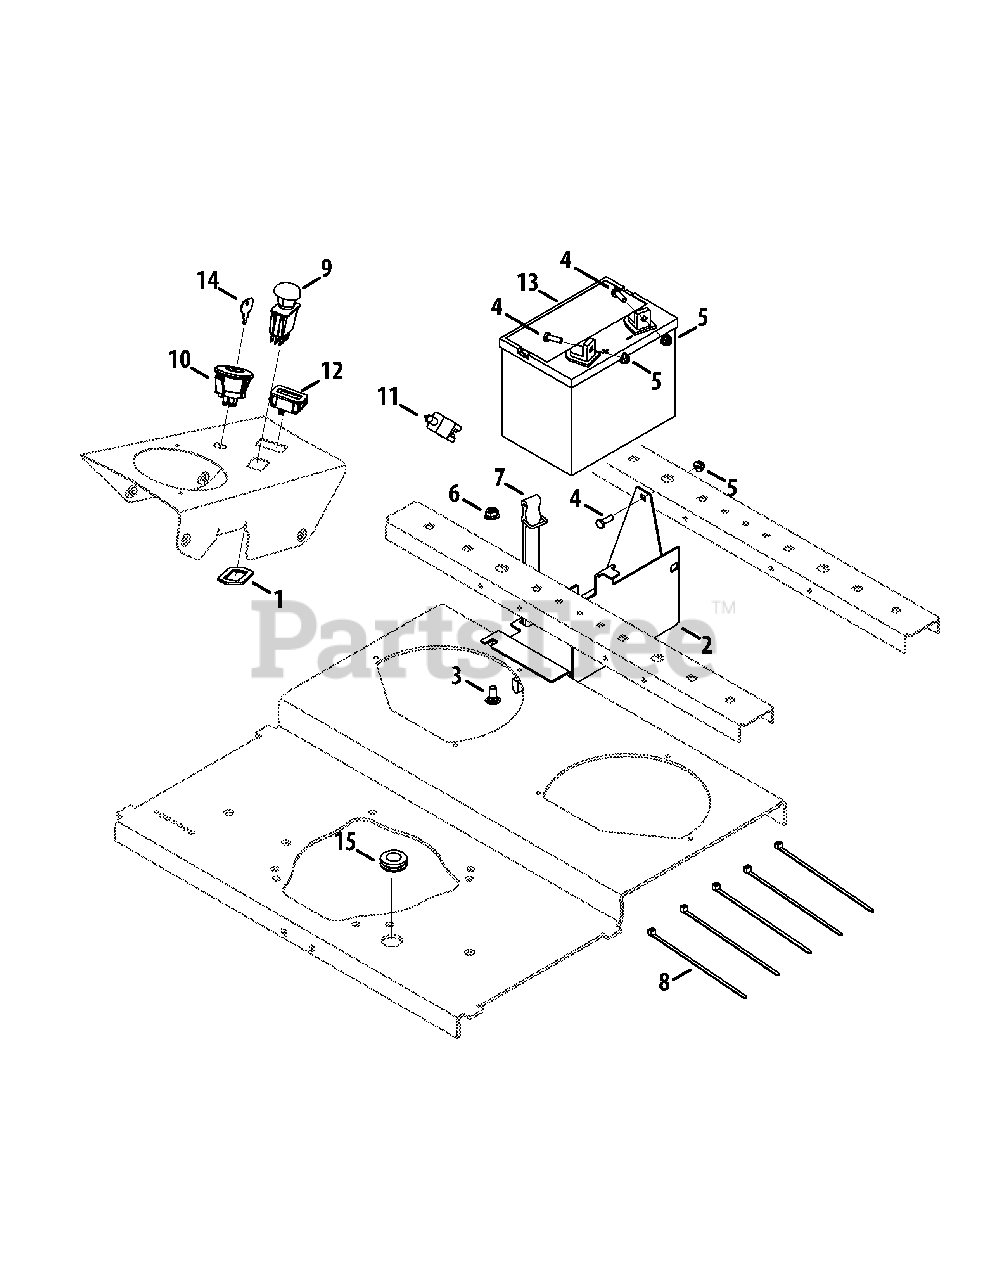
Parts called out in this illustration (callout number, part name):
1	PTO Switch Bracket
2	Battery Bracket
3	Carriage Bolt, 3/8-16 x .750
4	Hex Cap Screw, 1/4-20 x .75
5	Nut, 1/4-20, Flangelock
6	Nut, 3/8-16, Flangelock
7	Battery Strap
8	Cable Tie
9	Electric PTO Switch
10	Key Switch
11	Plunger Switch, NO/NC
12	Hour Meter
14	Key
15	Rubber Grommet, .75 x 1.062 x .50
